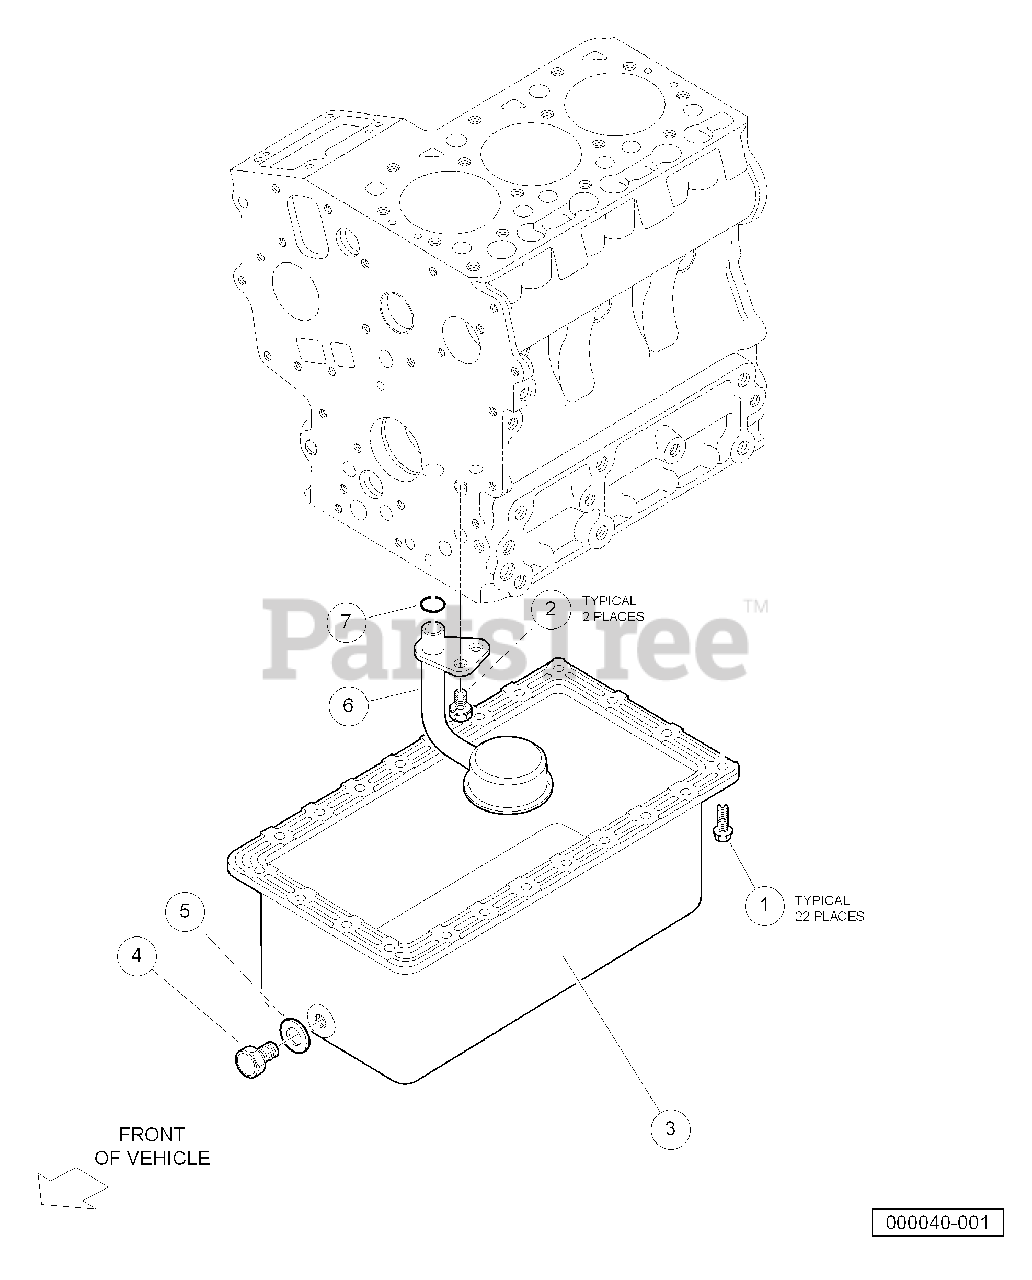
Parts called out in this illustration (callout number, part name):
1	Bolt, M6 X 1 X 14
2	Bolt, M8 X 1.25 X 15
4	Plug, Drain, M12 X 14
5	Gasket, 20 X 13
6	Filter, Oil, Pick Up
7	O Ring, 20 X 17
